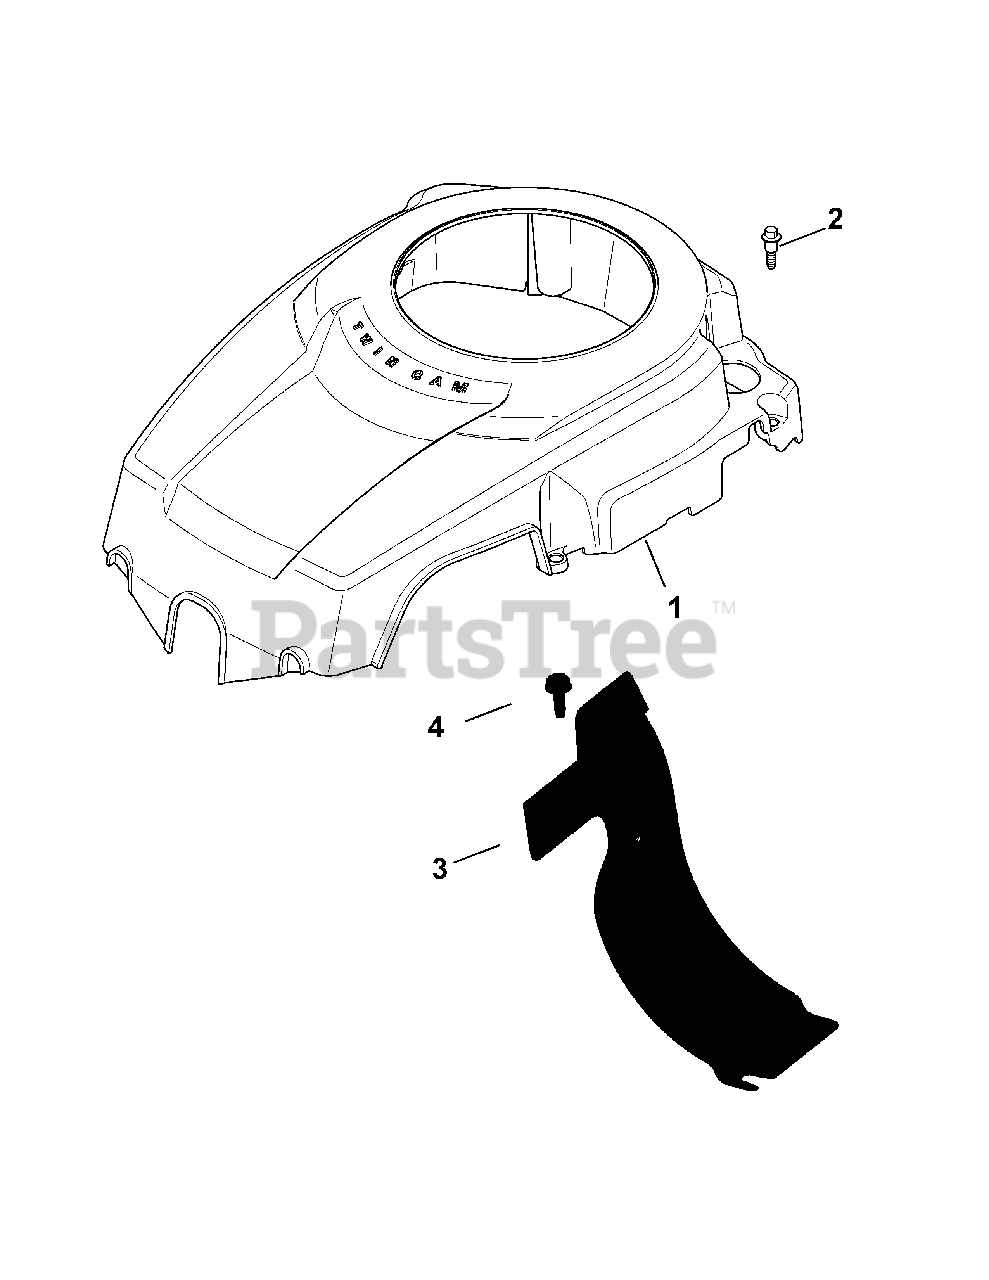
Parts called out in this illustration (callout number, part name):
1	Blower Housing
2	Shd. Thd. Frm. Screw, M6 X 1 X 26
3	Baffle Baarrel
4	Thread Forming Screw
